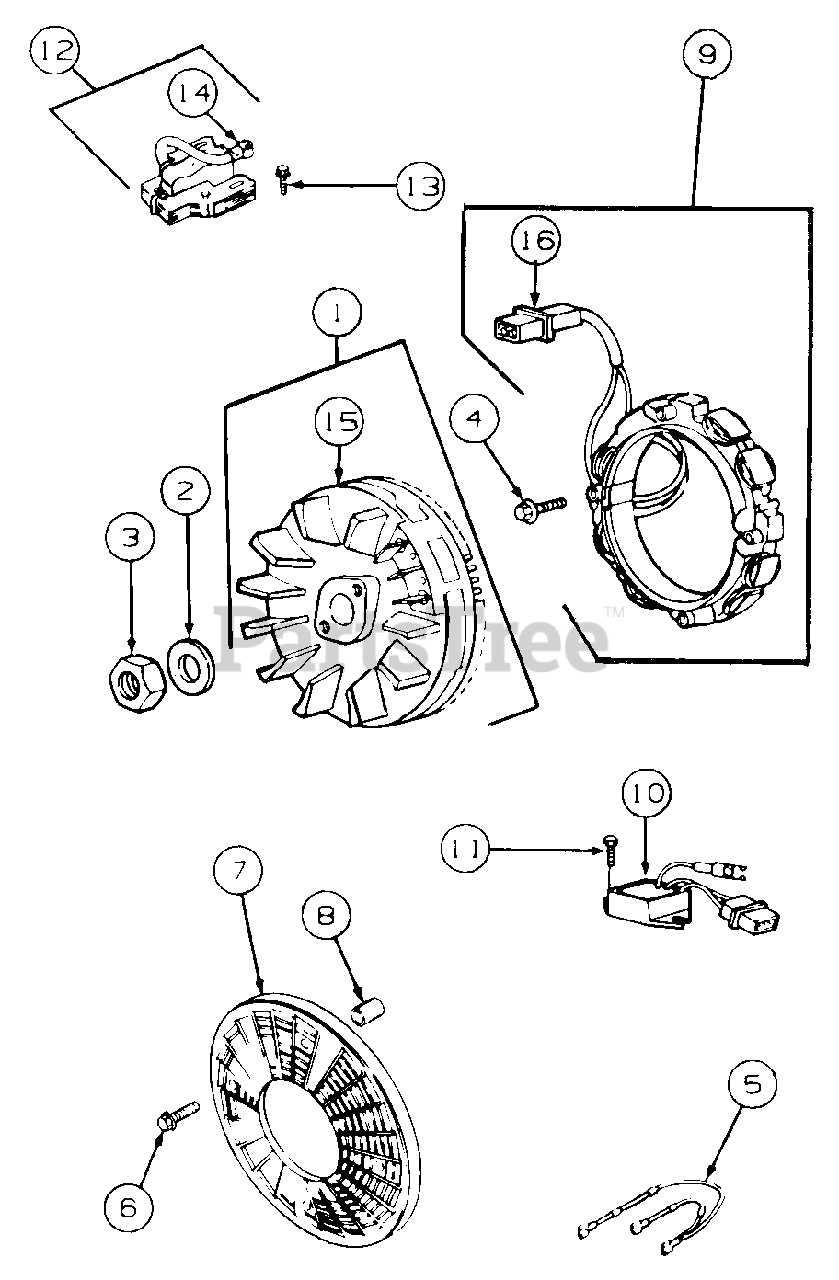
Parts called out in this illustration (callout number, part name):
1	Flywheel & Ring Gear
2	Washer, Spring
4	Screw, Mounting
5	Wire, Ground
6	Screw, Sems
7	Screen, Rotating
8	Spacer
9	Stator, 16 Amp
10	Regulator
11	Screw, Mounting
12	Armature
13	Screw, Mounting
14	Terminal
15	Gear, Flywheel Ring
16	Diode & Connector Assembly
